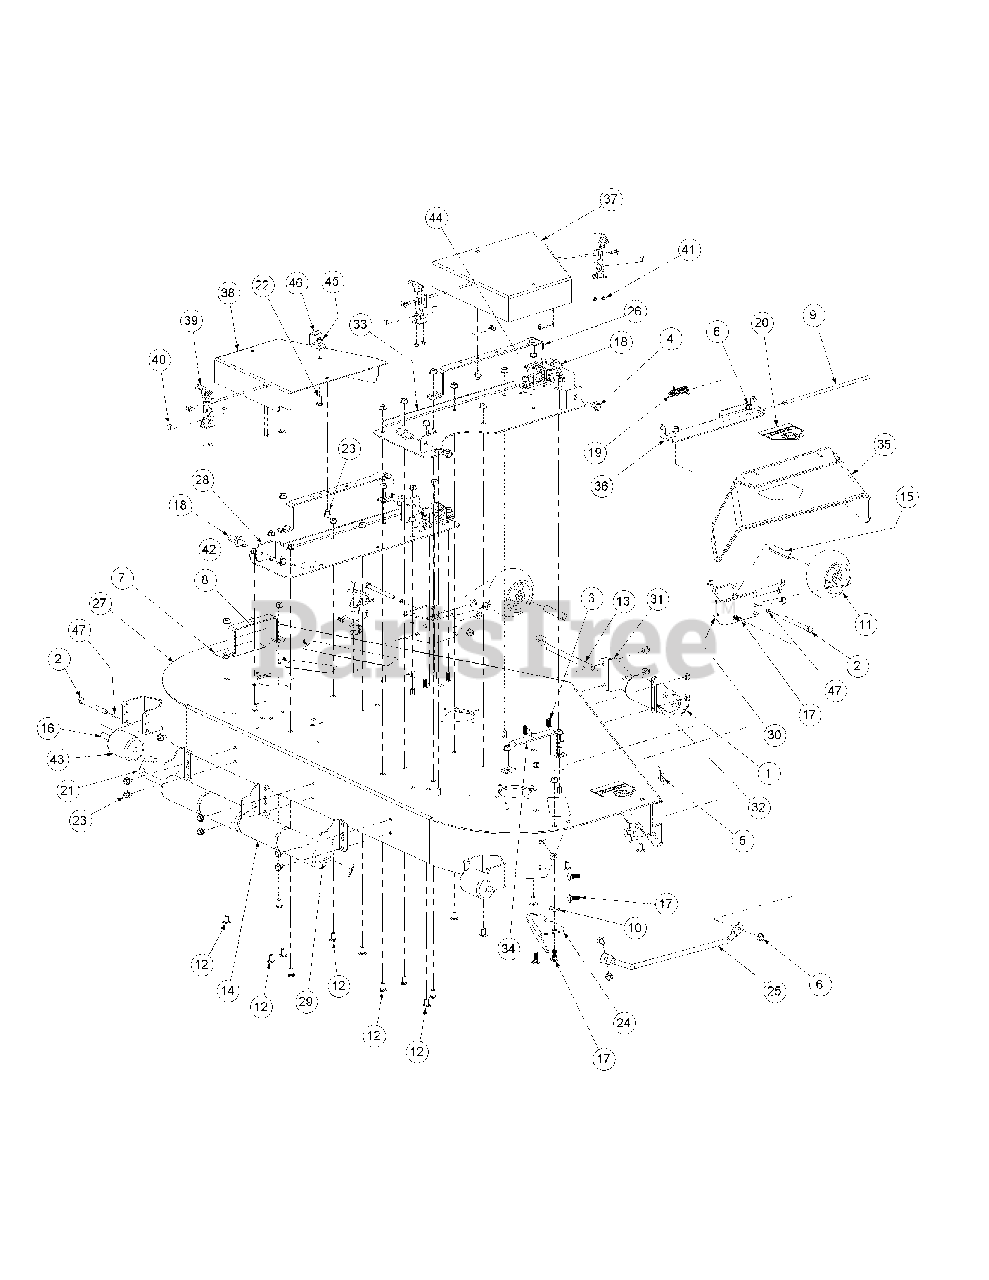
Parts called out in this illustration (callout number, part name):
1	Cotter Pin, .125 Dia. x 1.0
2	Hex Cap Screw, 3/8-16, 3.75
3	Carriage Screw, 3/8-16 x 1.25
4	Lock Nut, Nylon Insert, 1/2-13
5	Label, 60"
6	Flange Lock Hex Nut, 3/8-16
7	Decal, Rotating Blade
8	Decal, Warning Shield Missing
9	Chute Deflector Rod
10	Idler Washer
11	Complete Wheel, 5.00 Dia.
12	Carriage Bolt, 3/8-16 x .75 Lg.
13	Roller Pin, 1/2 Dia. x 7.31 Lg.
14	Front Roller
15	Wheel Spacer
16	Spacer, .385 x .50 x 3.045
17	Carriage Bolt, 3/8-16 x 1
18	Pin, 5/8 Dia. x 1.2 Lg.
19	Torsion Spring, 0.4ID x 2.16Lg
20	Decal, Danger Hand and Feet
21	Roller Pin
22	Hex Cap Screw, 5/16-18 x .75
23	Hex Index Washer Screw, 3/8-16, .5
24	Chute Bracket
25	Finger Guard
26	Belt Cover Support
27	60 Deck Assembly
28	Left Hand Mount Deck Bracket Assembly
29	Deck Roller Mount Bracket
30	Anti-Scalp Wheel Front Mount Bracket
33	Right Hand Deck Bracket Assembly
34	Outer Belt Cover Support Assembly
35	Chute Deflector
36	Chute Deflector Bracket
37	Right Hand Deck Belt Cover
38	Left Hand Deck Belt Cover
39	T-Handle Latch Draw
40	Phillips Head Screw, 10-32
41	Lock Nut, Nylon Insert, 10-32
42	Commercial Mower Label
43	Grass Catcher Roller
44	Pillow Block
45	Nut, 5/16-18, Hex Flange Lock
46	Stop Bracket
47	Flat Washer, 3/8
